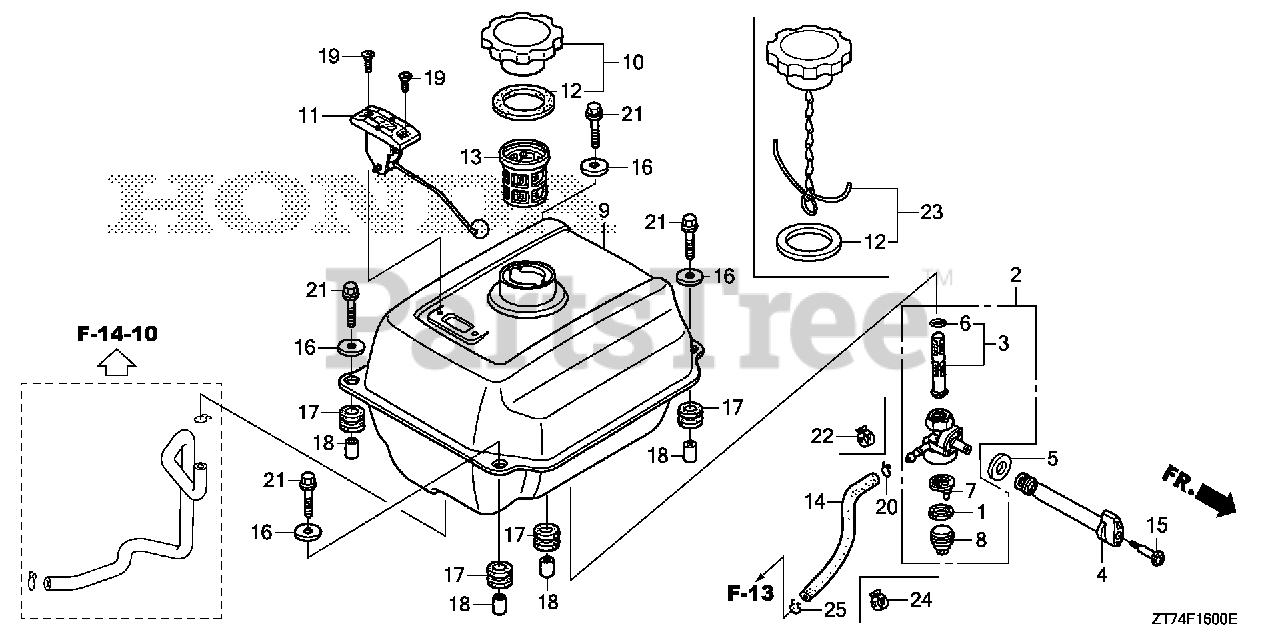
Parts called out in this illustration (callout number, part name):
1	GASKET, FUEL STRAINER CUP
2	PETCOCK ASSY.
3	SCREEN SET, FUEL STRAINER
4	LEVER, PETCOCK
5	SEAL, PETCOCK LEVER
6	O-RING (9.0X1.3)
8	CUP, FUEL STRAINER
9	TANK, FUEL *TBLACK* (BLACK)
11	METER ASSY., FUEL
12	GASKET, FUEL FILLER CAP
13	FILTER, FUEL
14	TUBE, FUEL TANK (FKM) (NOT AVAILABLE)
15	SCREW, PAN (4X19)
16	WASHER, TANK CUSHION
17	CUSHION, TANK RUBBER
18	COLLAR, TANK CUSHION
19	SCREW, FLAT (5X10)
21	BOLT, FLANGE (6X22)
22	CLIP, TUBE (D8)
23	CAP, FUEL FILLER
24	CLIP, TUBE (D8.5)
